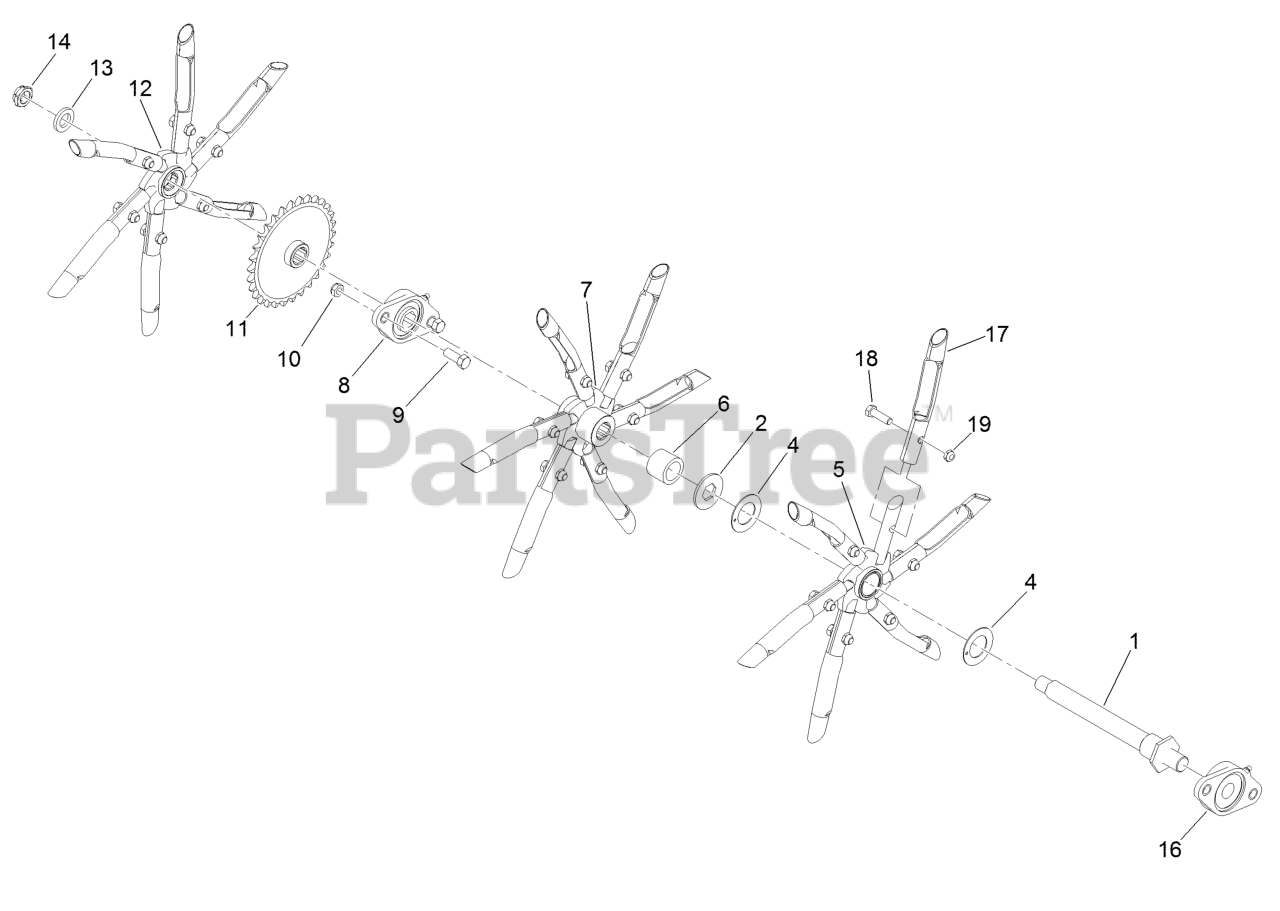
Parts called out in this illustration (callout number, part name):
1	Tine Shaft ASM
2	Keeper-Tine, Floating
4	Washer-Thrust
5	Floating Spyder ASM
6	Spacer-Tine
7	Driven Spyder ASM
8	Bearing-Hex Bore
9	Screw-HH
10	Nut-Lock
11	Sprocket ASM
12	Driven Spyder ASM
13	Washer-Spacer
14	Nut-Lock
16	Bearing-Round Bore
17	Tine-Coring (3/4 Inch)
18	Screw-HH 3/8-16 X 1 1/4
19	Nut-Nyloc 3/8-16 Thin
